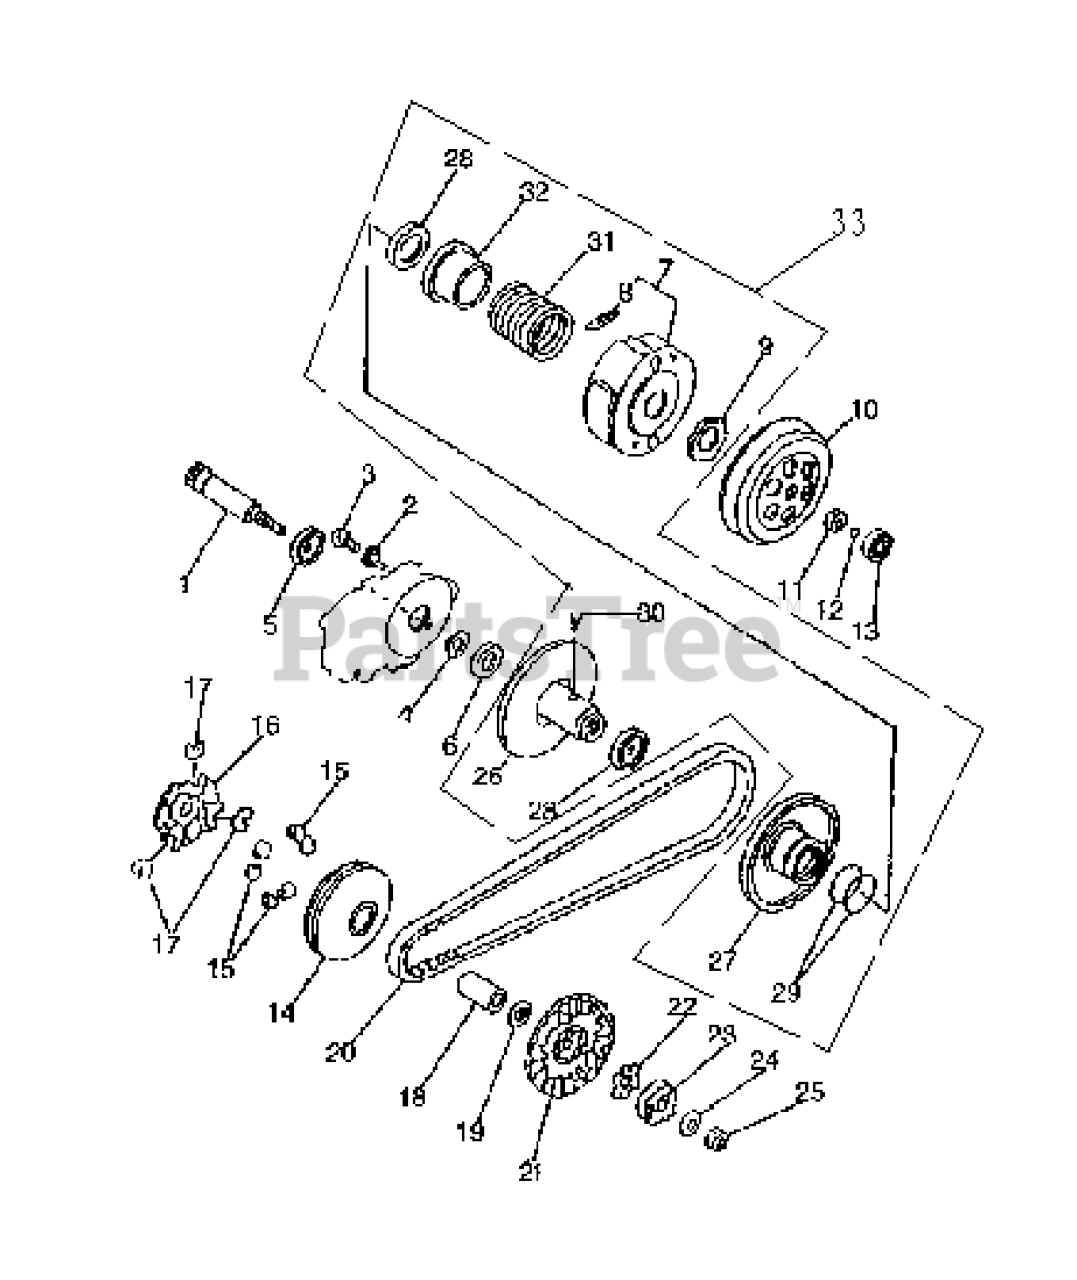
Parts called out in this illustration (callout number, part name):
1	PRIMARY DRIVE GEAR
4	CIRCLIP
5	ROLING BEARING
6	OIL SEAL
7	SHOE CLUTCH ASSY,
8	SPRING
10	HOUSING
13	BEARING
14	FACE, MOVABLE DRIVE
16	PLATE, MOVABLE DRIVE
17	DAMPER
20	V BELT, DRIVE
21	FACE, FIXED DRIVE
22	PLATE, WOODRUFF KEY
23	STARTING DISC
24	WASHER, SPRING
26	FACE, FIXED DRIVEN
27	FACE, MOVABLE DRIVEN
28	OIL SEAL
30	PIN, GUIDE
32	SEAT, SPRING
33	DRIVEN PULLEY and CLUTCH ASSY
